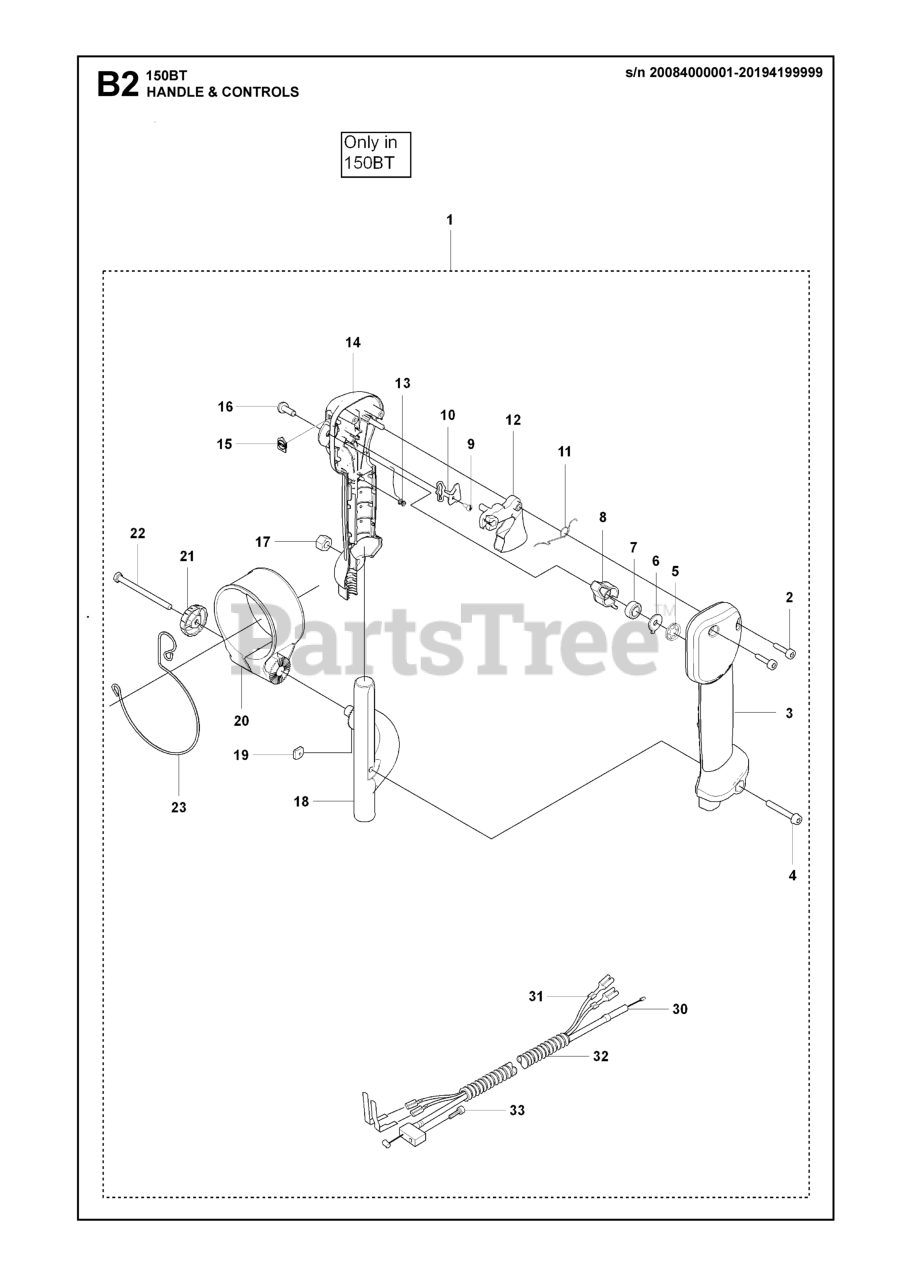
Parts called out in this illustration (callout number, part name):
1	HANDLE ASSY 150BT
3	HANDLE HALF (R)
4	SCREW
7	SPRING RUBBER
8	LEVER STOP
12	TRIGGER 848L5W34C0
14	HANDLE HALF (L)
16	SHAFT PIVOT
18	HOLDER, HANDLE
20	HOLDER TH
21	KNOB
30	CABLE COMP
31	RP CORD
